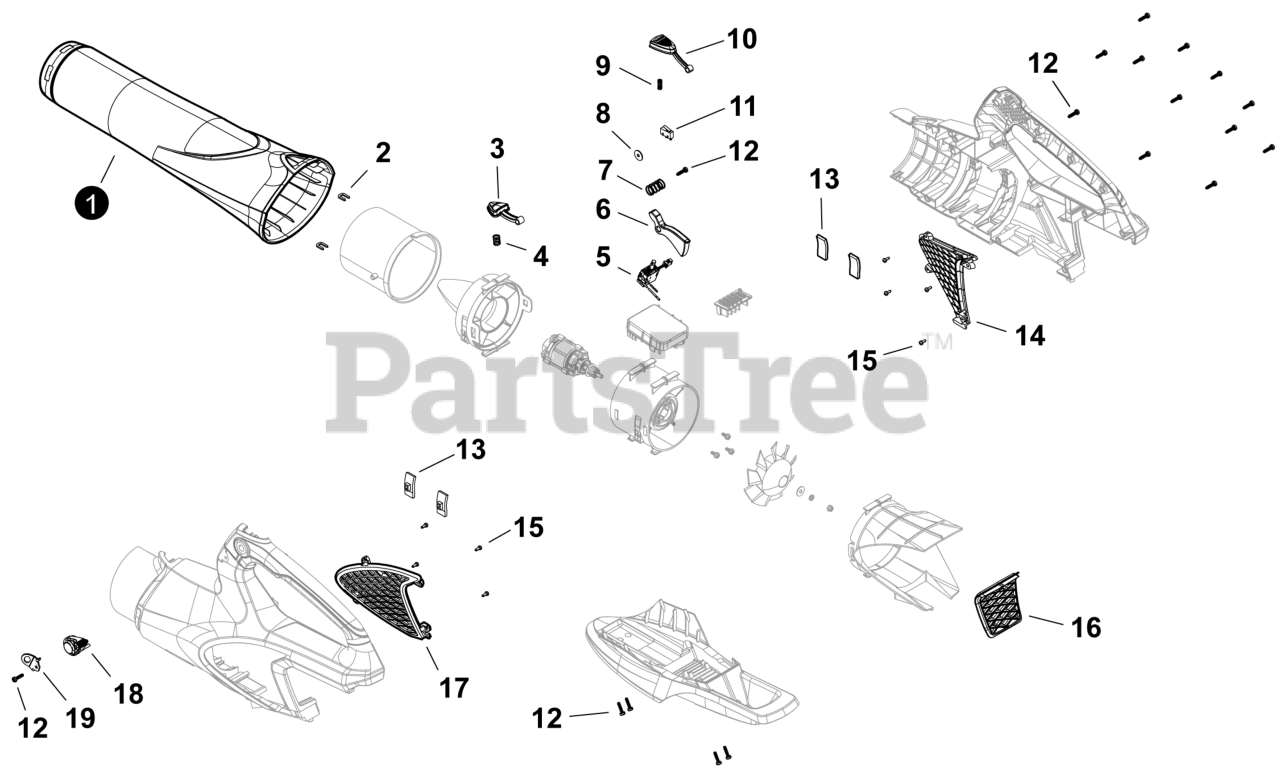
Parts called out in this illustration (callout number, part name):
1	TUBE, BLOWER W/ WEAR RING
2	RETAINER
3	BUTTON, RELEASE
4	SPRING, COMPRESSION
5	SWITCH, SPEED-CONTROL
7	SPRING, COMPRESSION
10	BUTTON, TURBO
11	SWITCH, MICRO
13	INSULATOR, MOTOR
14	VENT, RIGHT
16	VENT, REAR
17	VENT, LEFT
18	KNOB, CRUISE CONTROL
19	HOOK, STRAP
